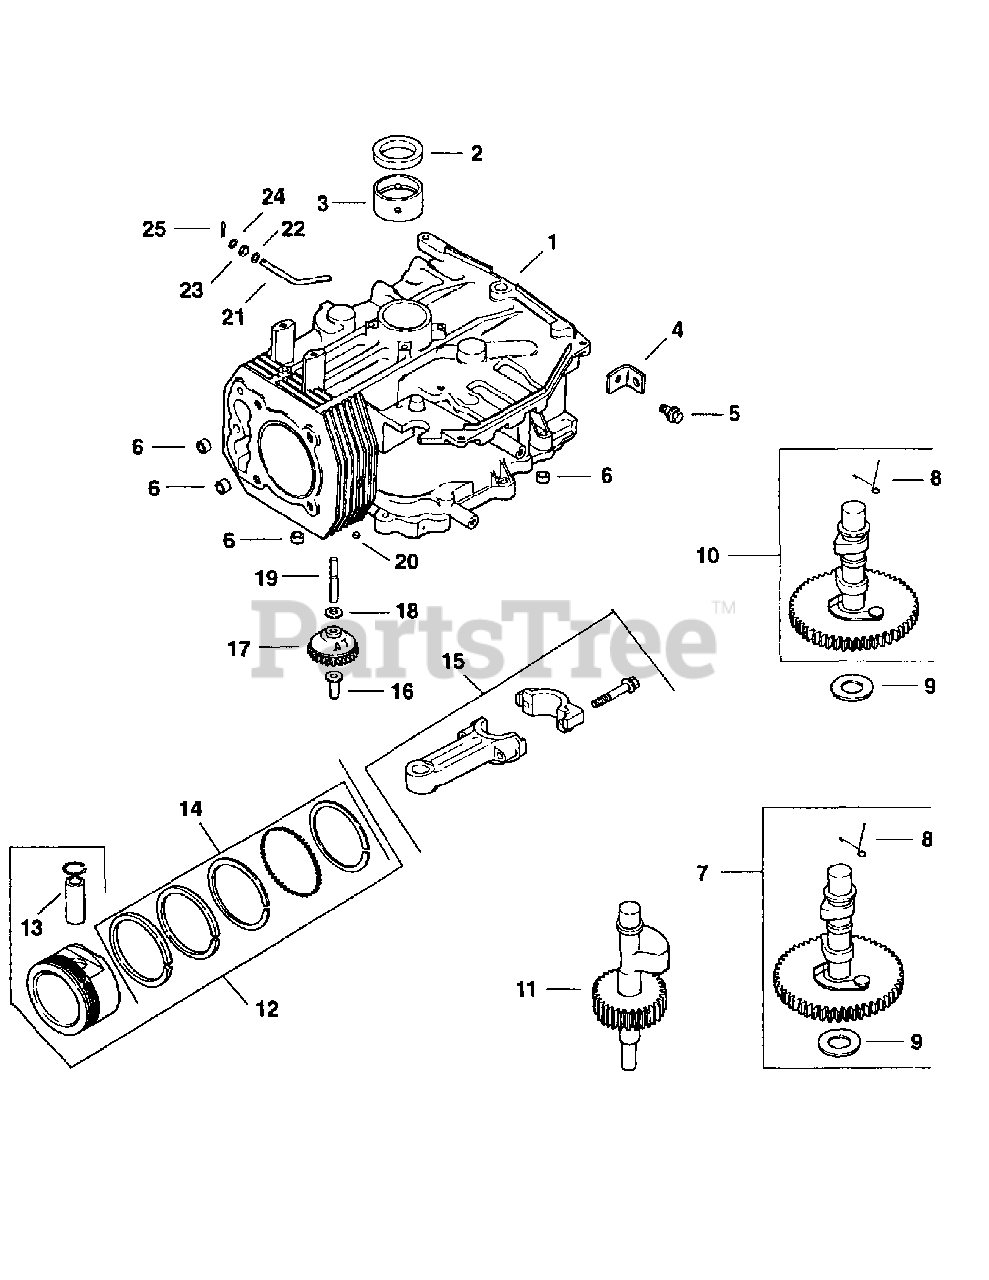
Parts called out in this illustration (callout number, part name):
1	Crankcase
2	Seal, Crankshaft
3	Bearing, Crankshaft (Std.)
3	Bearing, Crankshaft (.25)
3	Bearing, Crankshaft (.50)
4	Strap, Lifting
5	Screw, Lifting Strap M8 x 1.25 x 25
6	Dowel, Locating
7	Kit, Camshaft
8	Spring, Actuating (ACR)
9	Shim, Camshaft (A.R.) (White)
9	Shim, Camshaft (A.R.) (Blue)
9	Shim, Camshaft (A.R.) (Green)
9	Shim, Camshaft (A.R.) (Yellow)
9	Shim, Camshaft (A.R.) (Red)
9	Shim, Camshaft (A.R.) (Gray)
9	Shim, Camshaft (A.R.) (Black)
11	Shaft, Balance
12	Piston w/Ring Set (Std.)
12	Piston w/Ring Set (.25)
12	Piston w/Ring Set (.50)
13	Retainer, Piston Pin
14	Ring Set (Std.)
14	Ring Set (.25)
14	Ring Set (.50)
15	Connecting Rod (Std.)
15	Connecting Rod (.25)
16	Pin, Governor Regulating
17	Gear, Governor
18	Washer, Governor Gear Thrust
19	Shaft, Governor Gear
20	Plug, Cup
21	Governor Cross Shaft Kit
22	Washer, Plain 1/4"
23	Seal, Governor Cross Shaft
24	Washer, Governor Shaft
25	Pin, Governor Hitch
